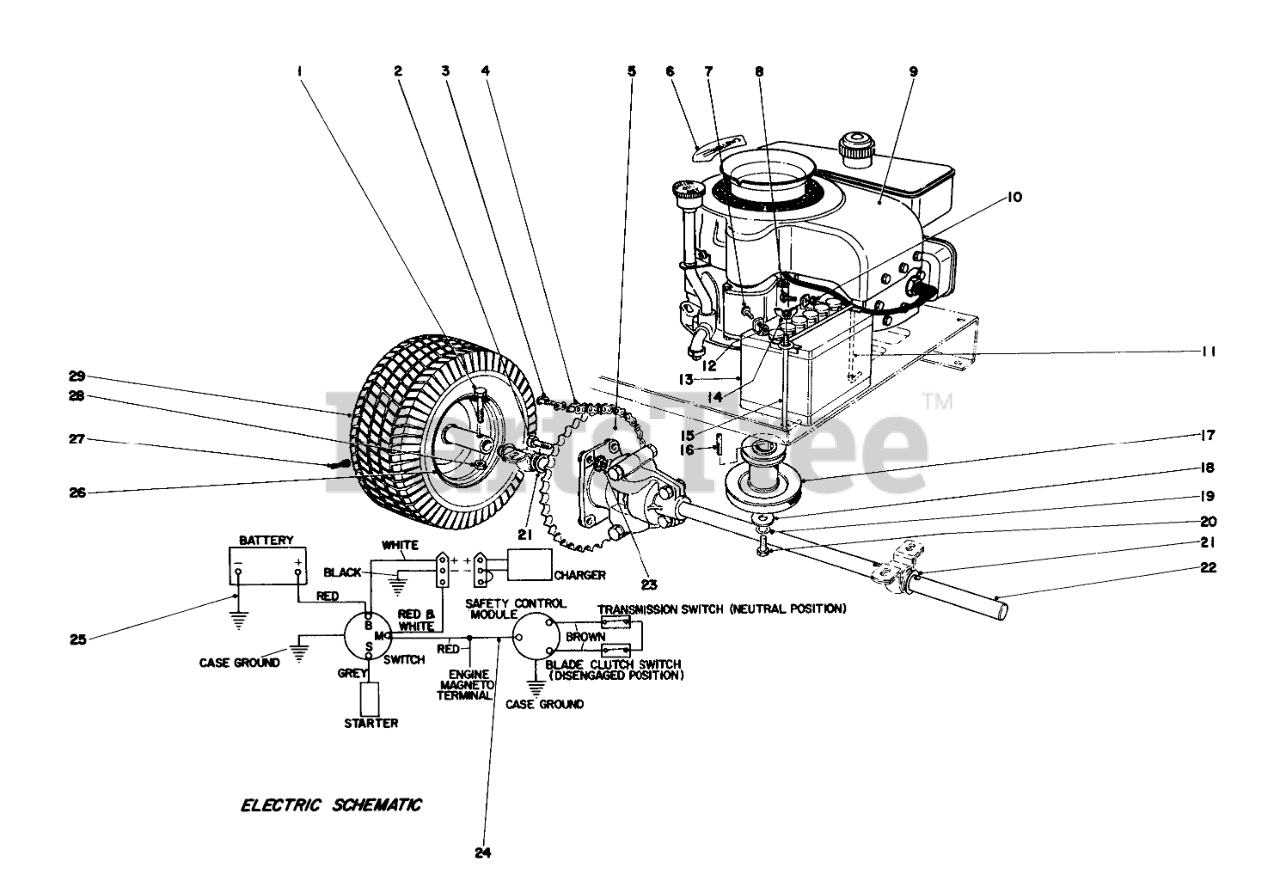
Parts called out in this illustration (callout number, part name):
1	SCREW-HH
2	SCREW-HH
3	LINK-CONNECTING
4	Roller Chain
5	Sprocket
6	Decal
7	SCREW-HH
8	SCREW-HH
9	Engine
10	NUT-HEX
11	Battery Clamp
12	NUT-HEX
13	Battery
14	NUT-WING SPECL
15	ROD-SUPPORT, BATTERY
17	Pulley
18	Washer
19	WASHER-LOCK
20	SCREW-HH
21	WASHER
22	Differential
23	NUT-LOCK, CONE
24	Wiring Harness
25	ENG-GROUND WIRE ASM
27	STEM-VALVE
28	NUT-LOCK, CONE
29	Tire
